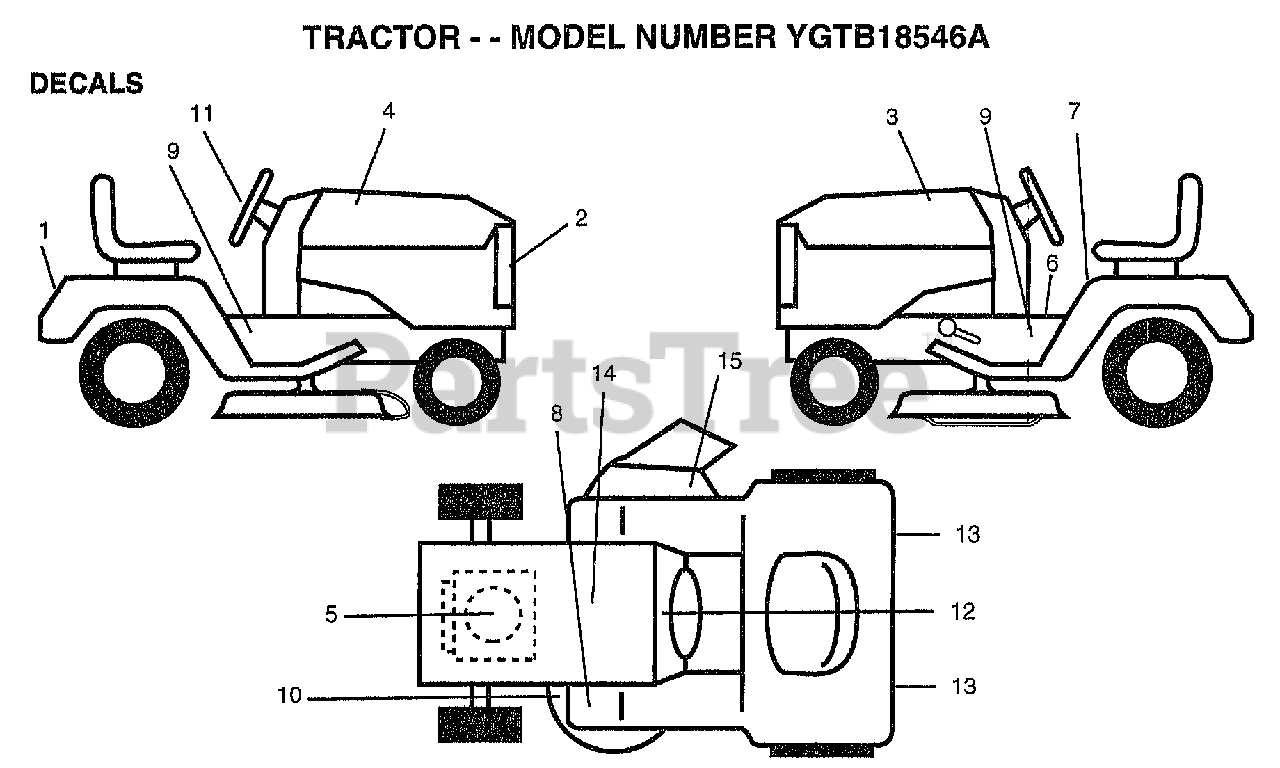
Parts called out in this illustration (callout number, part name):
1	DECAL FENDER
3	DECAL HOOD LH18.6
4	DECAL HOOD RH18.5
5	DECAL.HP.ENGINE
6	"DECAL.OPER,SDL"
7	DECAL.CAUT.ENG/FR
8	DECAL T
9	"DECAL CHASSIS,46"""
11	"DECAL INSERT,STRG"
13	REFLECTOR-TAIL YT
14	DECAL.BATRY.3-3908
15	"DECAL, WARNING"
